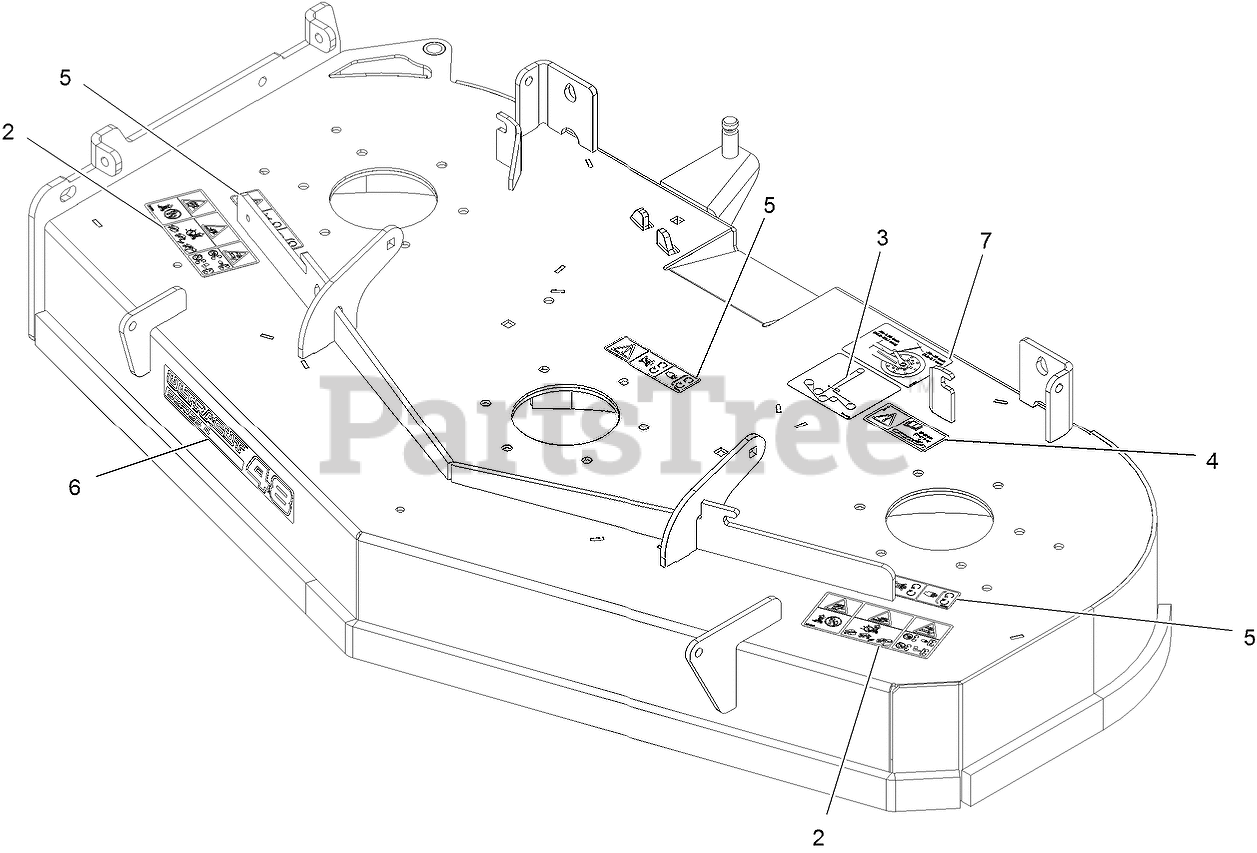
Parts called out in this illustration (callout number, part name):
2	DECAL-WARNING THROWN OBJ
3	DECAL-BELT ROUTING
4	DECAL-TORQUE, BOLT
5	DECAL-COVER, MISSING
6	DECAL, 484
7	DECAL-BELT GUIDE DIST
